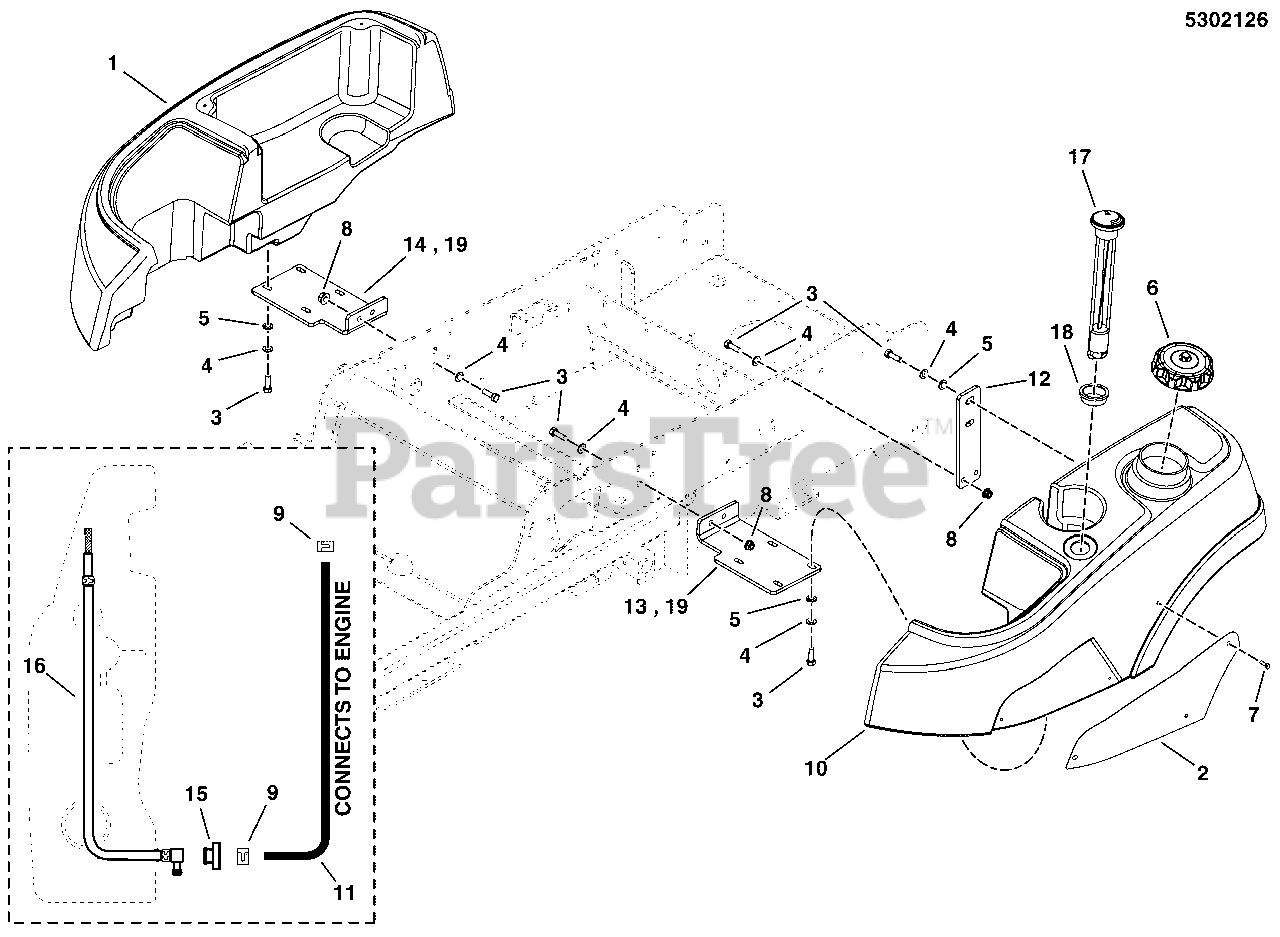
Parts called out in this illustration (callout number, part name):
1	TANK, FENDER, CONZ, RH
2	PLATE,FUEL TANK BADGE
3	BOLT, 5/16-18 X 3/4 GD5
4	WASHER, 5/16 SAE
5	WASHER, 5/16 LOCK YZ
6	FUEL CAP, 3-1/2", MANAGED VENT OUT, 12"
7	SCREW, #10-24 X 3/8 ALLEN BHBZ
8	NUT, 5/16-18 HEX NYLOCK FLANGE
9	CLAMP, HOSE, EXTERNAL, 1/2 - RED
10	TANK, FUEL, LH
11	HOSE, 1/4" FUEL, 20.00"
12	MOUNT, FUEL TANK, REAR - BLK
13	MOUNT, FUEL TANK, FRONT - BLK
14	MOUNT, FENDER, FRONT - BLK
15	BUSHING-FUEL TANK RED RUBBER (SV)
16	PICKUP TUBE ASM, FUEL TANK (SV)
17	GAUGE, FUEL (SV)
18	GROMMET, FUEL GAUGE (SV)
19	MOUNT, FENDER, FRONT - BLK
